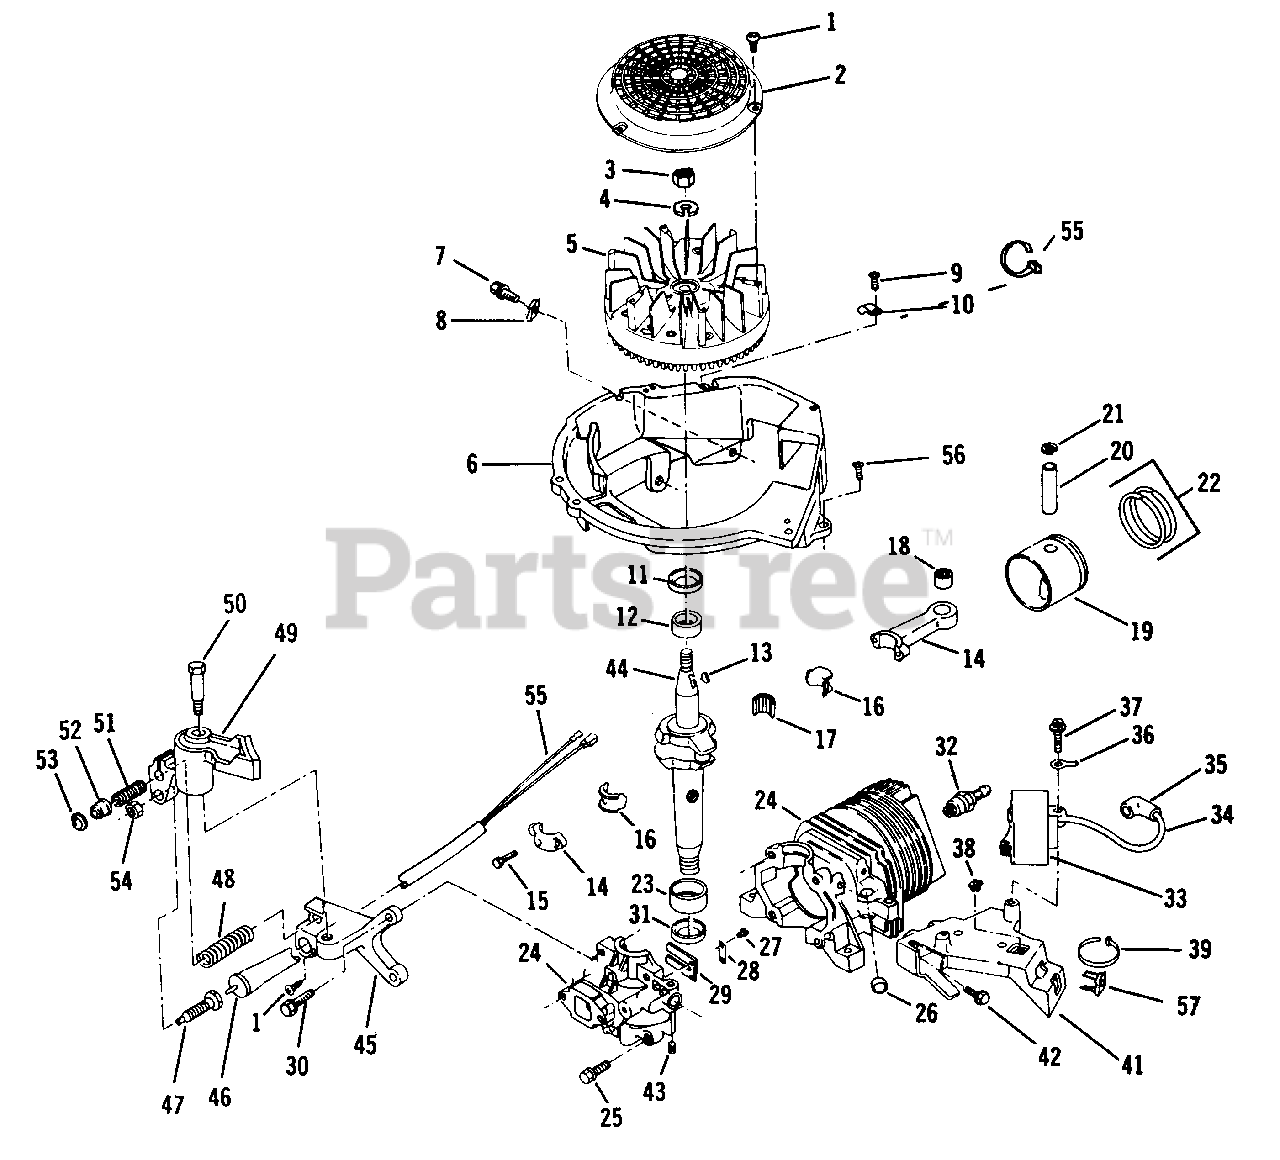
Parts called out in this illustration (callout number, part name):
1	Screw-Flywheel Screen and Switch
2	Screen-Flywheel
3	Nut-Flywheel
4	Lockwasher
5	Flywheel Assembly
6	Base-Shroud
7	Screw
8	Clip-"J"
9	Screw-Clamp to Shroud Base
10	Clamp
11	Oil Seal-Upper
12	Bearing-Main-Upper
13	Key-Flywheel
14	Conn. Rod Assembly
15	Screw-Cap
16	Liner Split
17	Needle Bearing Set
18	Bearing Assembly
19	Piston and Ring Set
20	Wrist Pin
21	Retaining Ring
22	Ring Set
23	Bearing-Main-Lower
24	Cylinder and Crankcase Cover Assembly
25	Screw-Cover to Crankcase
26	Plug
27	Screw-Reed to C'case Cover
28	Plate-Reed Hold Down
29	Reed
30	Screw-Brake Mtg. Brk't.
31	Oil Seal-Lower
32	Spark Plug
33	C. D. Ignition Module and Lead Assembly
34	High Tension Lead and Lower Assembly
35	Spring Terminal
36	Terminal-Ground Lead
37	Screw-C.D. Mounting
38	Grommet-C.D. Bracket
39	Tie Strap
41	Bracket-C.D. Mounting
42	Screw
43	Set Screw-Starter Assembly
44	Crankshaft
45	Bracket-Brake
46	Brake Switch Assembly
47	Plunger
48	Spring-Brake
49	Brake Assembly
50	Bolt-Shoulder
51	Spring-Cable Retainer
52	Actuator-Brake Lever
53	Retainer
54	Nut
55	Tie Strap
56	Screw-Shroud Base to C.D. Brk't.
57	Grommet
57	Clip
